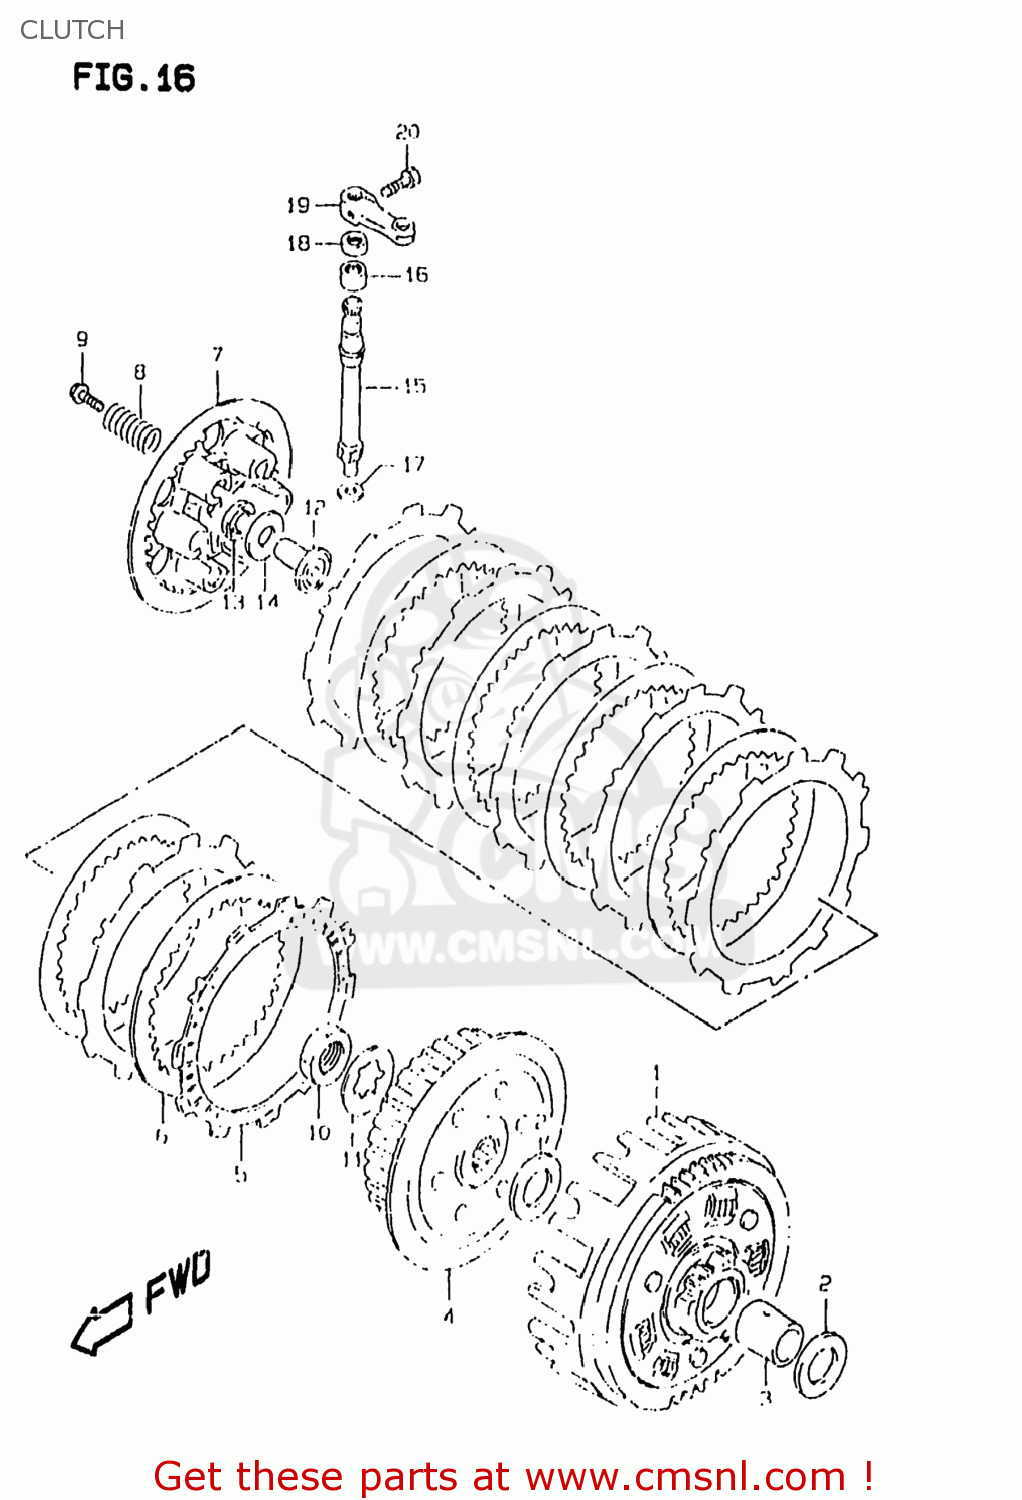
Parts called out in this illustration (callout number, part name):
1	GEAR ASSY,PRI DRIVEN(64/15
2	WASHER
3	SPACER(20X25X29)
4	HUB,CLUTCH SLEEVE
5	PLATE,CLUTCH DRIVE (NAS)
6	PLATE,CLUTCH DRIVEN(T:1.6) (NAS)
7	DISC,CLUTCH PRESSURE
8	SPRING
9	BOLT 5X16
10	NUT
11	WASHER,LOCK
12	RACK,CLUTCH RELEASE
13	BEARING(10X24X2)
14	WASHER
15	PINION,CLUTCH RELEASE
16	BEARING(12X16X10)
17	SHIM(8.8X14X1)
18	SEAL,OIL(10X17X5)
19	ARM,CLUTCH RELEASE
20	BOLT
